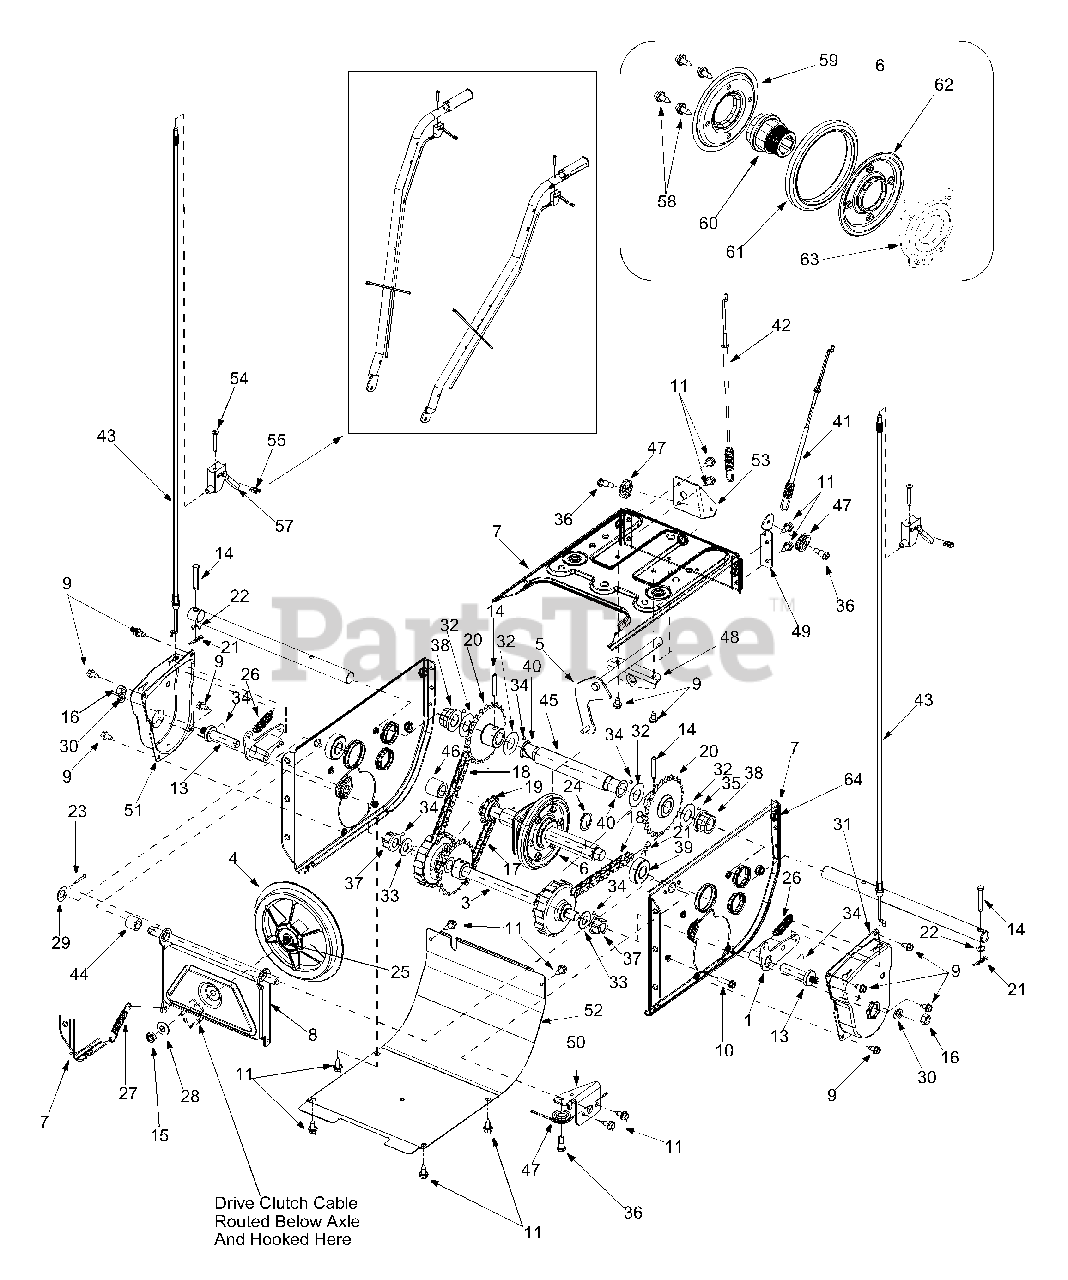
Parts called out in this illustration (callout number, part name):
1	Dogg Assembly: RH
2	Dogg Assembly: LH
3	Shift Assembly: Steerable Drive
4	Friction Wheel Disc Assy.
6	Bearing
7	Transmission Frame Assembly
10	Hex Washer Screw 1/4-20 x 1
11	Hex Screw 1/4-20 x .625"
12	Drive Shaft
13	Actuator Shaft
15	Jam Nut 3/8-24 Gr.8
16	Hex Nut: 3/8-16
17	Chain
18	Chain
19	Sprocket: 10T
20	Sprocket
21	Cotter Pin
22	Flat Washer
23	Cotter Pin
24	Snap Ring
25	Adhesive: Loctite
26	Extension Spring
27	Extension Spring
28	Bell Washer
29	Flat Washer
30	Lock Washer
33	Flat Washer
34	Lubricant: 6 in 1
35	Grease
36	Shoulder Screw
37	Hex Flange Bearing
38	Hex Flange Bearing
39	Ball Bearing
40	Flange Bushing
41	Auger Clutch Cable
42	Drive Clutch Cable
43	Steering Cable
44	Spacer
45	Axle Support Tube
46	Spacer
47	Roller Cable
55	Weld Nut
56	Cable Tie
57	Turn Trigger
58	Hex Washer Screw 1/4-20
59	Friction Plate
60	Friction Wheel Hub
61	Friction Wheel Rubber
62	Friction Plate
63	Friction Wheel Bearing
64	Nut, Insert 5/16-18
